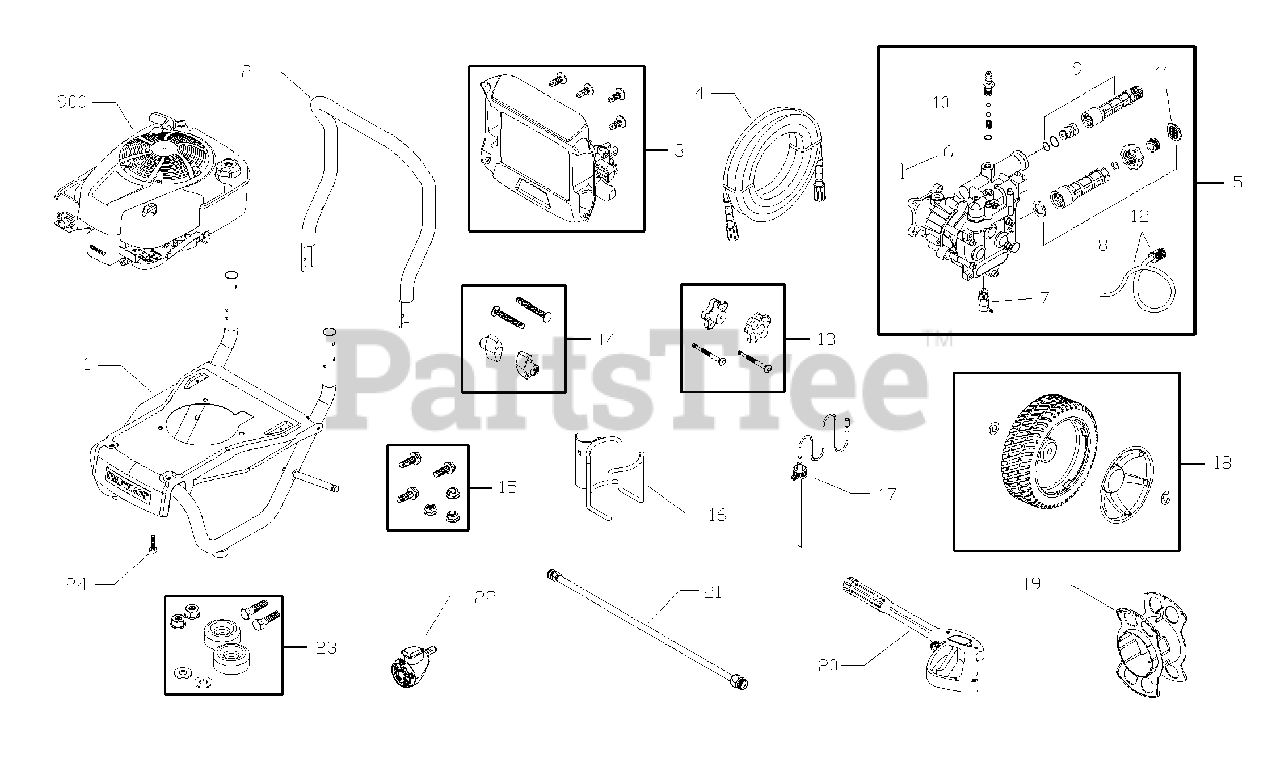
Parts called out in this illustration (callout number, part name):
1	BASE
4	HOSE
5	PUMP
7	VALVE, Thermal Relief
8	KIT, Water Inlet
9	KIT, Water Outlet
10	KIT, Chemical Injection
11	FILTER, Garden Hose
12	KIT, Chemical Hose
13	KIT, Hardware Handle
14	KIT, Hardware Handle
15	KIT, Hardware, Pump Mounting
20	GUN
21	EXTENSION, QC
22	NOZZLE, QC
23	KIT, Vibration Mount
900	*ENGINE
